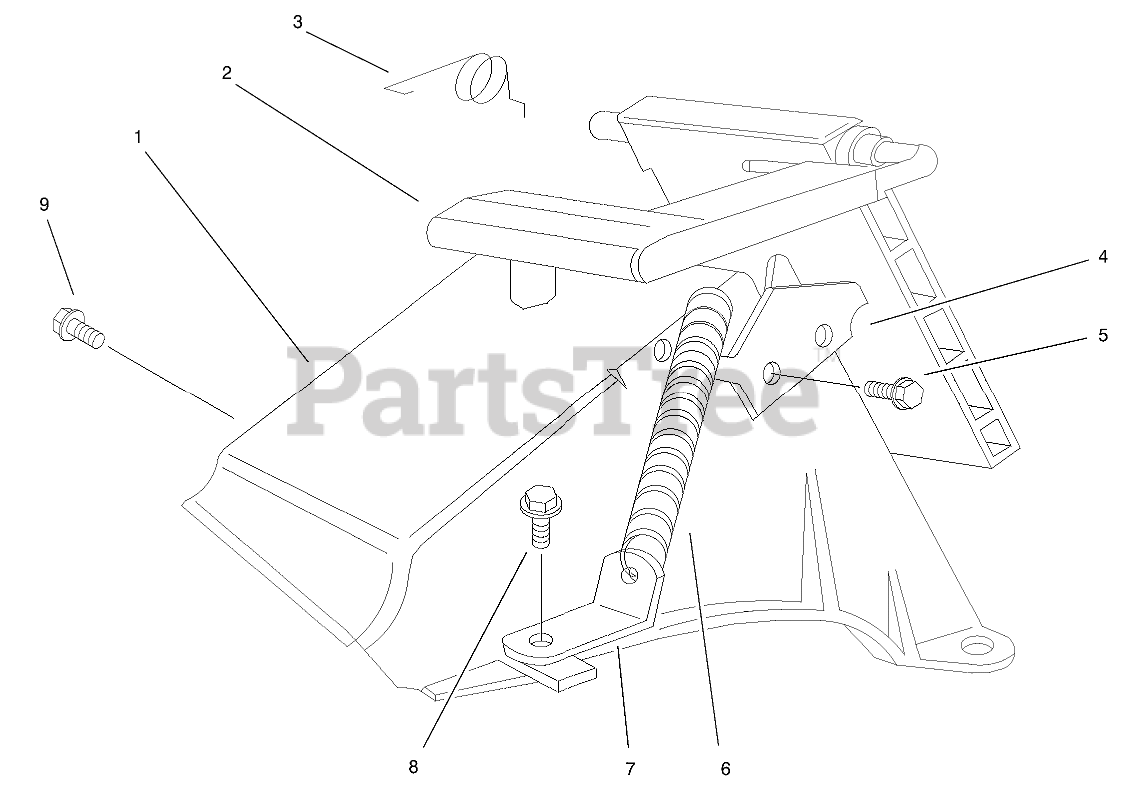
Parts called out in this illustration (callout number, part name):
1	Discharge Tunnel (Only On: 20043)
2	ASM-Discharge Door (Only On: 20043)
3	Spring-Door (Only On: 20043)
4	Latch-Plate (Only On: 20043)
5	Screw-Plastite (Only On: 20043)
6	Retainer-Door (Only On: 20043)
7	Bracket-Spring (Only On: 20043)
8	Screw & Washer ASM (Only On: 20043)
9	Screw & Washer ASM (Only On: 20043)
